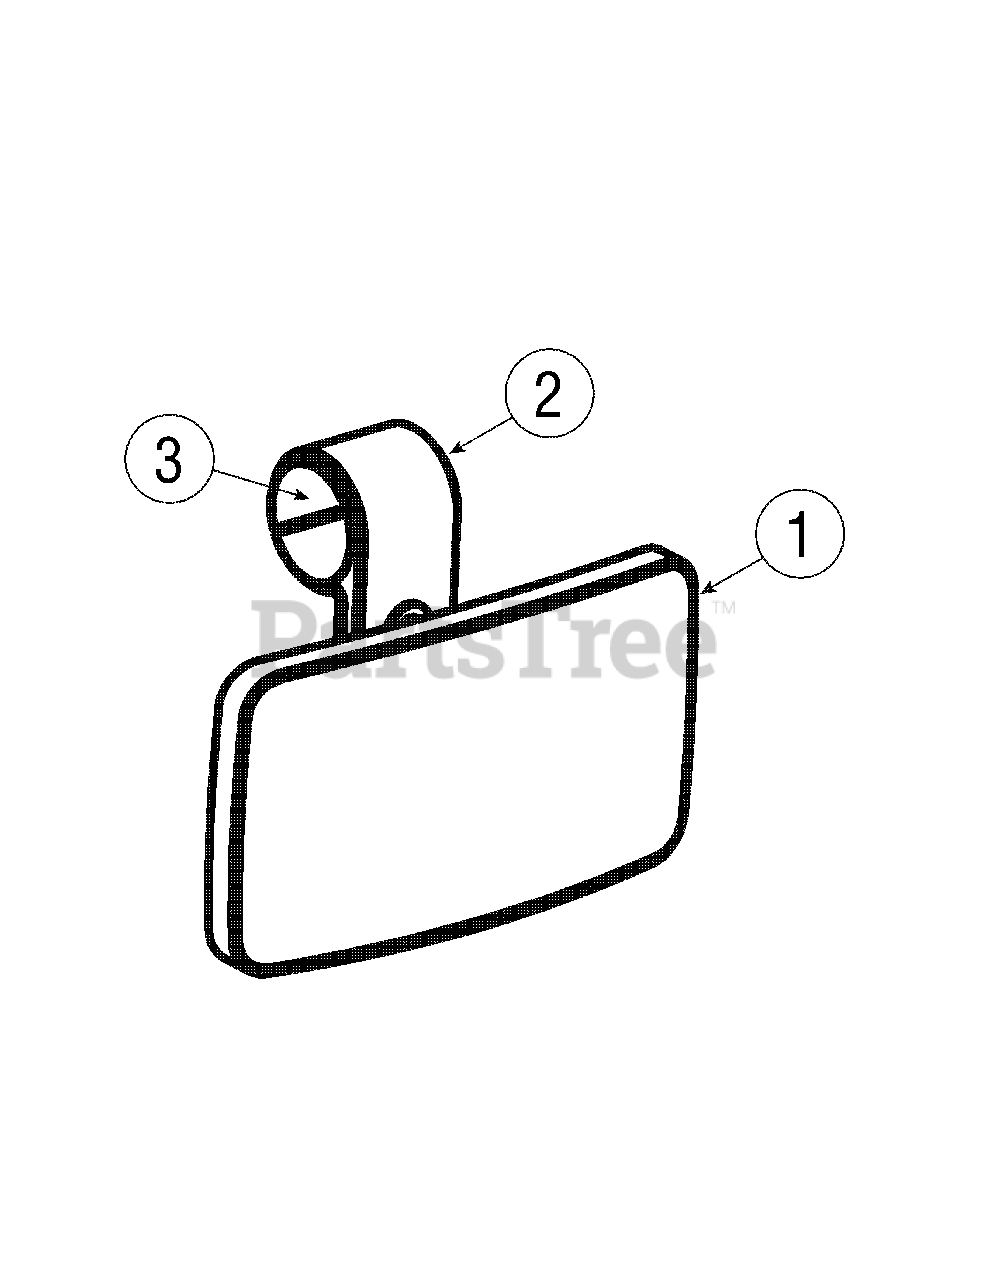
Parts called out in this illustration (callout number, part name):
1	Mirror Unit (Includes Hardware)
2	Clamp, Windshield
3	Clamp, Grip
